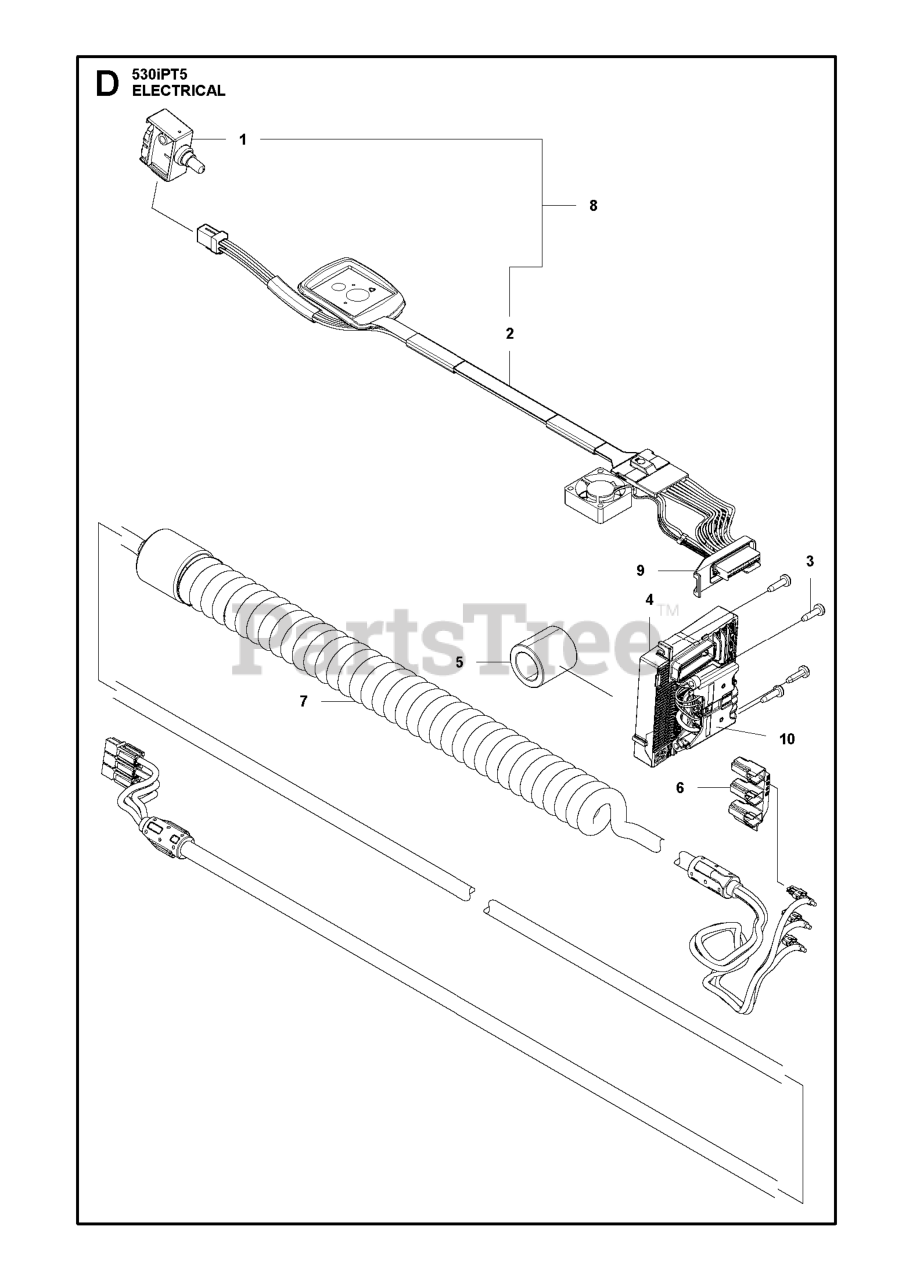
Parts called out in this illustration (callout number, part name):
1	TRIGGER SWITCH IPX4
2	WIRING ASSY POLE SAW MAIN
4	CONTROL UNIT BLDC - 536LIHE3
5	FERRITE CORE
6	HOUSING POWER TIMER, 3-POLE
7	WIRING ASSY TELESCOPIC POLESAW
8	SWITCH KIT BATTERY POLESAW 536
10	CONNECTOR BATTERY
